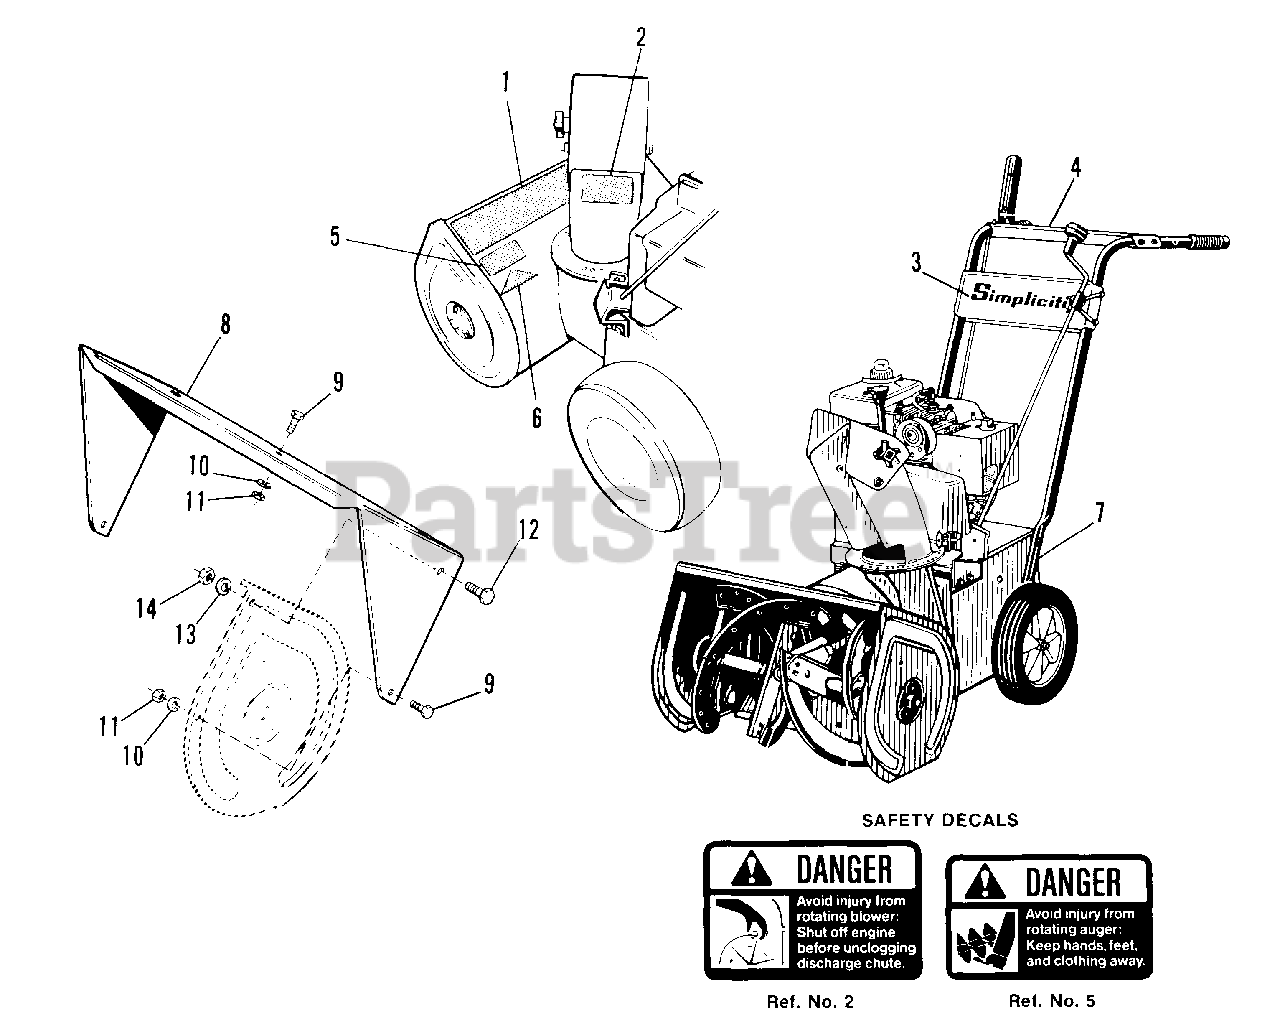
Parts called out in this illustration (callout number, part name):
1	DECAL Simplicity 450
2	DECAL, Danger, Blower
3	DECAL, Simplicity
4	DECAL, Dash
5	DECAL, Danger, Auger
6	DECAL, OPEI
7	I.D. PLATE, Simplicity
8	WRAPPER EXT. (Optional)
9	CAPSCREW, 1/4-20 x 1/2
10	LOCKWASHER, 1/0
11	NUT, Hex, 1/4-20
12	CAPSCREW, 5/16-18 x 5/8
13	LOCKWASHER , 5/16
14	NUT, Hex, 5/16-18
